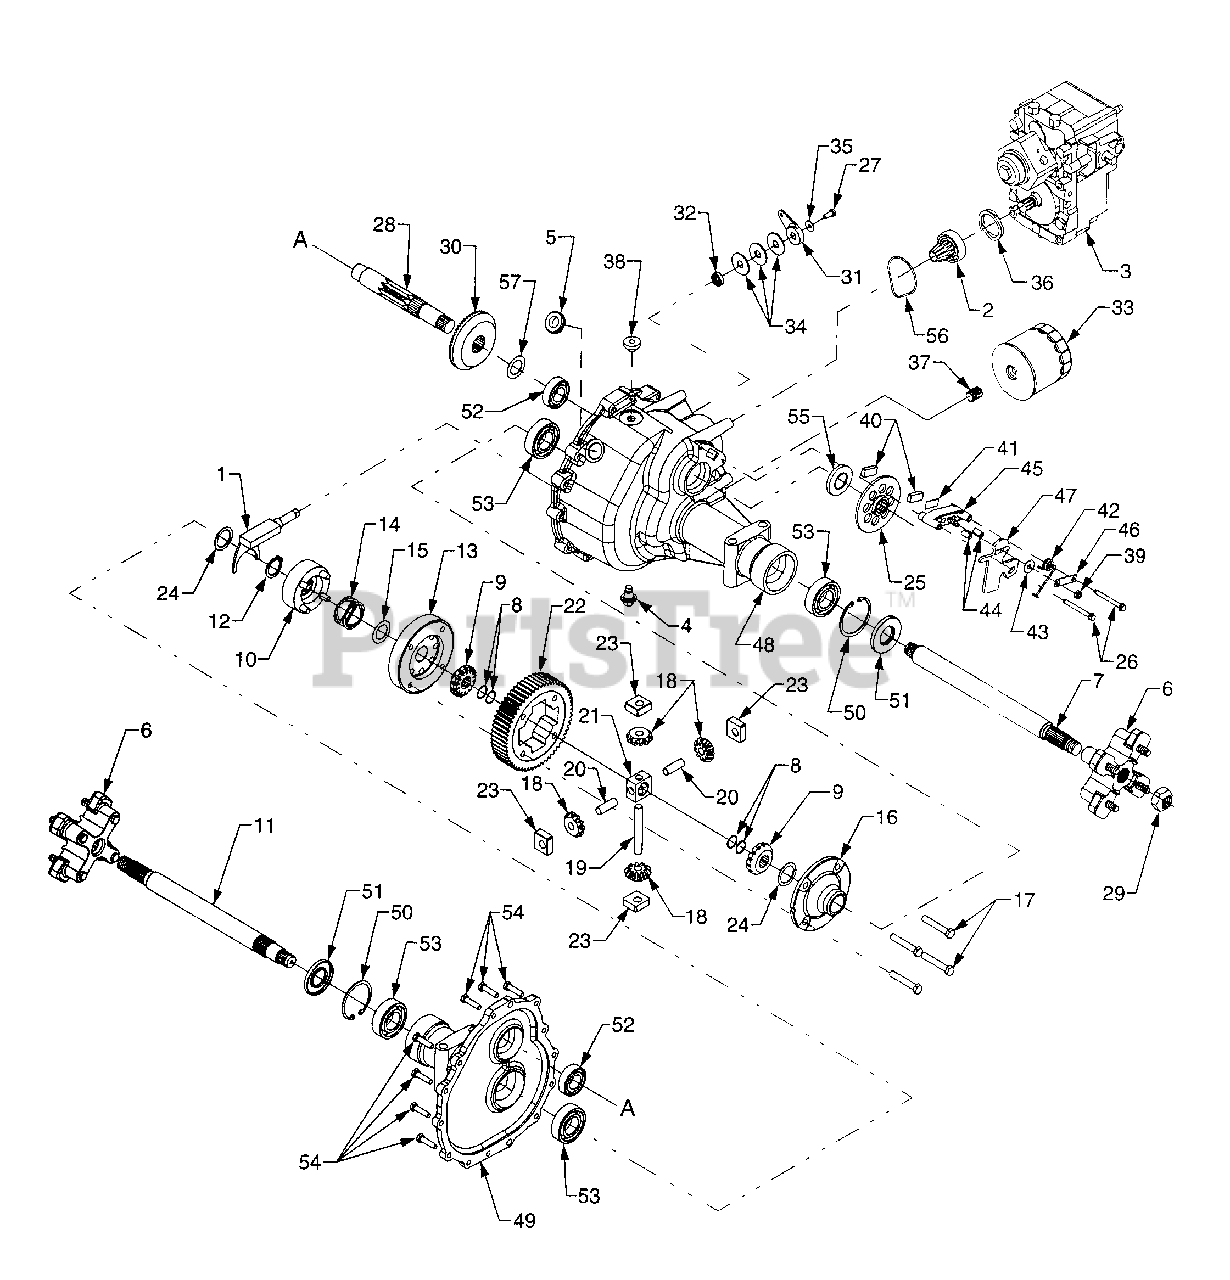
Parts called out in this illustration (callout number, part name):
1	Shaft, Differential Actuator
2	Gear Assembly, Pinion 13T
3	Hydrostatic Transmission Assy.
4	Plug, Drain, M14 x 1.5 x .827
5	Grommet, Rubber
6	Hub Assembly, Wheel
7	Axle Shaft, 15.08 Long - RH
8	Retaining Ring
9	Gear, Spur, 14T
10	Collar Assembly, Diff. Lock
11	Axle Shaft, 15.08 Long - LH
12	Retaining Ring
13	Housing, Diff. Lock
14	Spring, Compression
15	Washer, Thrust, 1.007 x 1.542 x .03
16	Housing, Diff. Cover
17	Hex Cap Screw, 3/8-24 x 2.25 GR8
18	Gear, Differential 10T
19	Shaft, Cross, .5 x 3.485
20	Shaft, Cross, Special
21	Differential Pinion Block
22	Gear, Spur 60T
23	Block, Thrust Miter
24	Washer, Flat, 1.187 x 1.56 x .062
25	Disc, Brake
26	Screw, Hex Wash. Hd. Tapp 1/4-20 x 2.375
27	Hex Cap Screw, 1/4-20 x .62 GR5
28	Shaft, Output 9T
29	Nut, Lock, 7/8-14
30	Gear, Bevel 54T
31	Arm, Diff. Lock Actuator
32	Seal, Oil
33	Filter, Oil
34	Washer, Flat, .51 x 1.5 x .07
35	Washer, Belleville, .265 x .75 x .062
36	Washer, Spring
37	Fitting, Filter Nipple
39	Nut, Hex Insert Lock, 5/16-24
40	Pad, Brake
41	Plate, Puck
42	Spring, Torsion
43	Washer, Flat, .343 x .88 x .062
44	Pin, Brake Actuator
45	Yoke, Brake
46	Bracket, Brake Anti-Rotation
47	Arm, Brake Actuator
48	Housing, RH
49	Housing LH
50	Retaining Ring
51	Seal, Oil
52	Bearing, Ball
53	Bearing, Ball
54	Screw, Hex Cap Locking 5/16-18 x 1.25 GR5
55	Seal, Oil 1.0 ID
56	Seal, Gland O-Ring
57	Washer, Flat, 1.0 x 1.56 x .030
